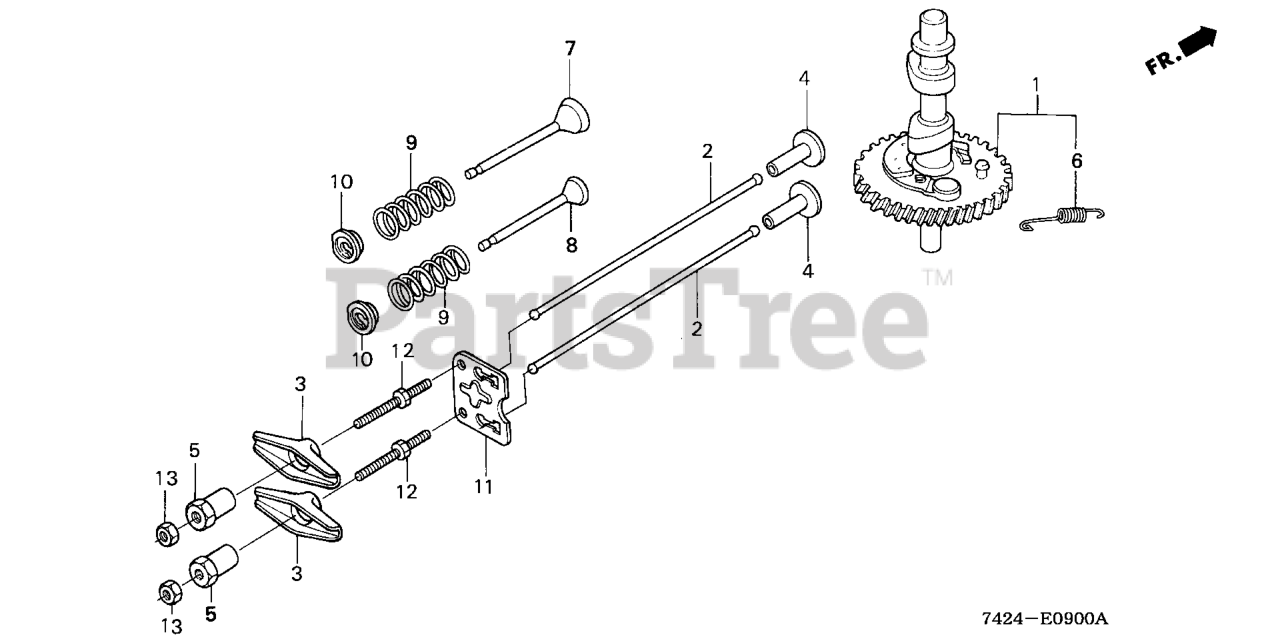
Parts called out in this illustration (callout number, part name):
1	CAMSHAFT ASSY.
2	ROD, PUSH
3	ARM, VALVE ROCKER
4	LIFTER, VALVE
5	PIVOT, ROCKER ARM
6	SPRING, WEIGHT RETURN
7	VALVE, IN.
8	VALVE, EX.
9	SPRING, VALVE
10	RETAINER, VALVE SPRING (EXHAUST SIDE)
11	PLATE, PUSH ROD GUIDE
12	BOLT, PIVOT (8MM)
13	NUT, PIVOT ADJ.
